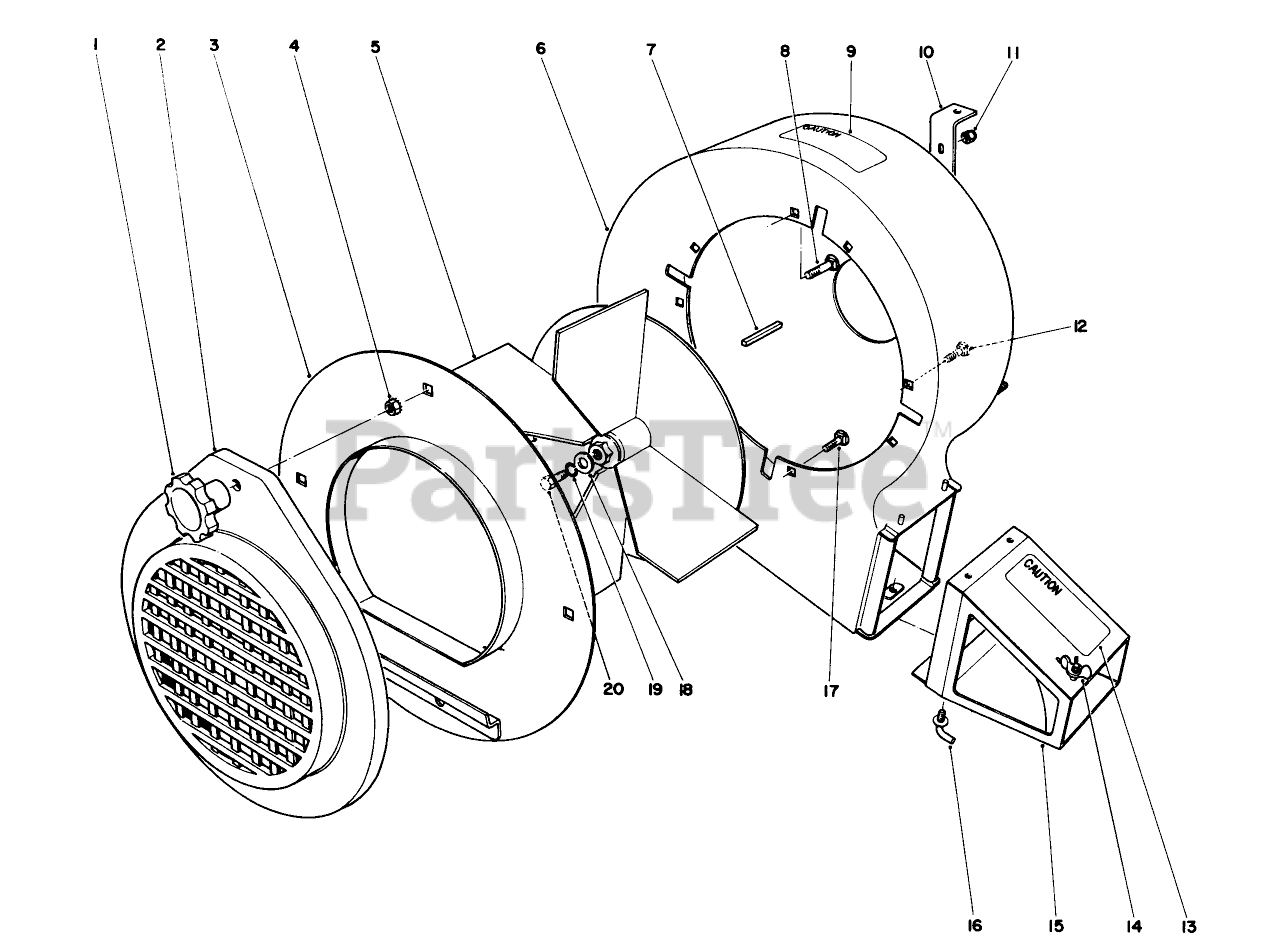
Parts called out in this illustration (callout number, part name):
2	INTAKE-BLOWER
3	Blower Cover
4	NUT-KEPS
5	Fan
6	Blower Housing
7	KEY-SQUARE
8	SCREW-CARR
9	Decal, Caution
10	Mounting Bracket
11	NUT-LOCK, NI
12	SCREW-CARR
13	EXHAUST DECAL
14	WING NUT
15	EXHAUST BLOWR WA/DECAL
16	ADJ SCREW 1/4-20X 3/4
17	SCREW-CARR
18	WASHER-FLAT
19	WASHER-LOCK
20	SCREW-HH
